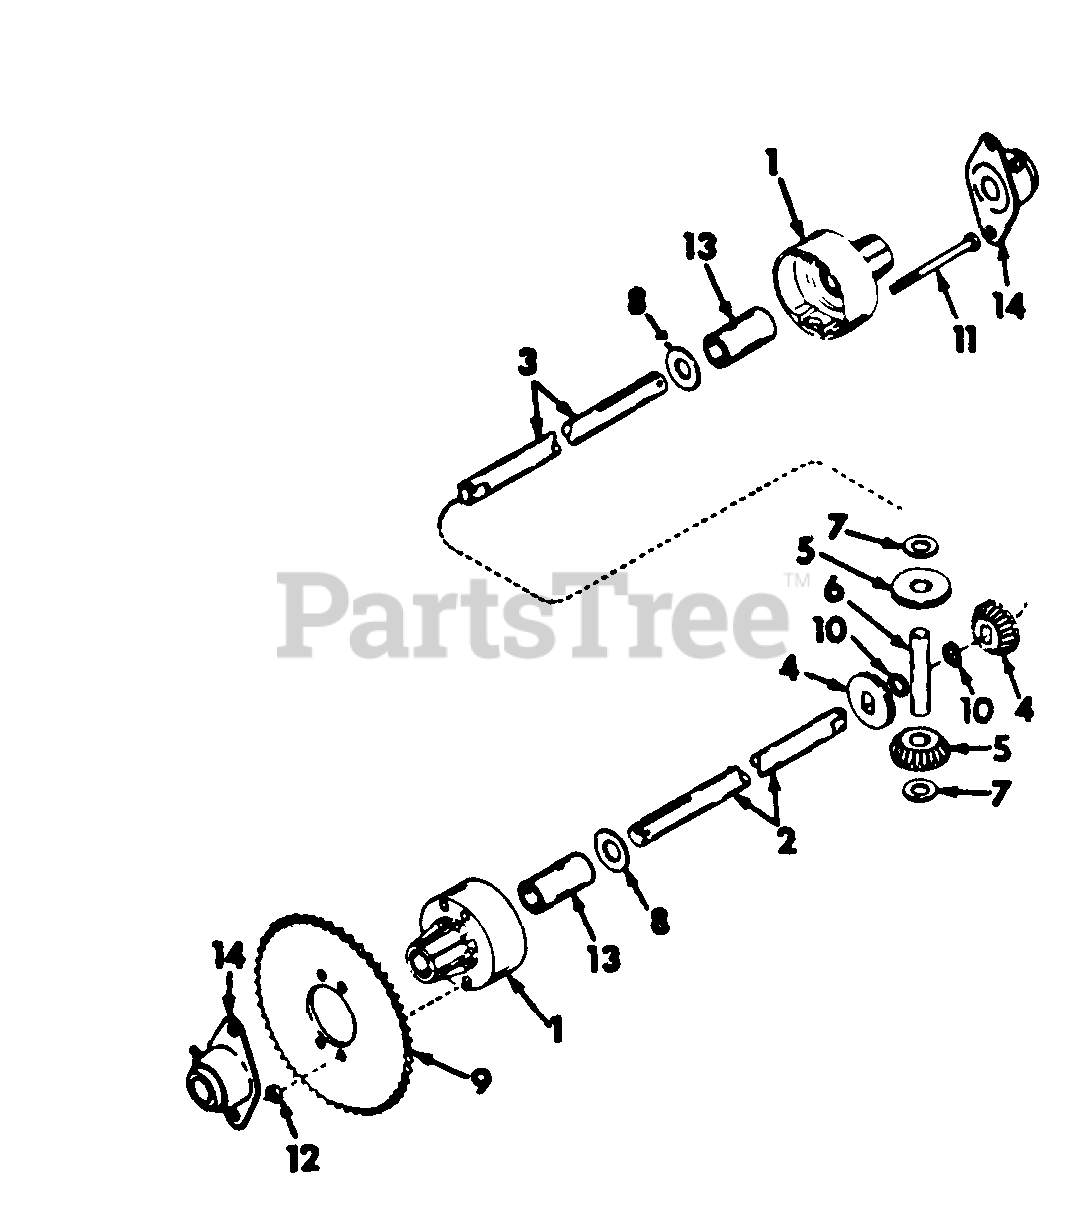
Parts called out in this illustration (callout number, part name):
1	HOUSING, DIFFERENTIAL CARRIER SPROCKET SIDE
2	AXLE, SHORT
4	GEAR, BEVEL -16 T
5	GEAR, PINION -16 T
7	WASHER, THRUST BRG RACE
9	SPROCKET, 45 T
10	RING, 689 HVY EXT RET
11	SCREW, 5/16-18 SPECIAL
12	NUT, 5/16-18 LOCK
14	BEARING, REAR AXLE
